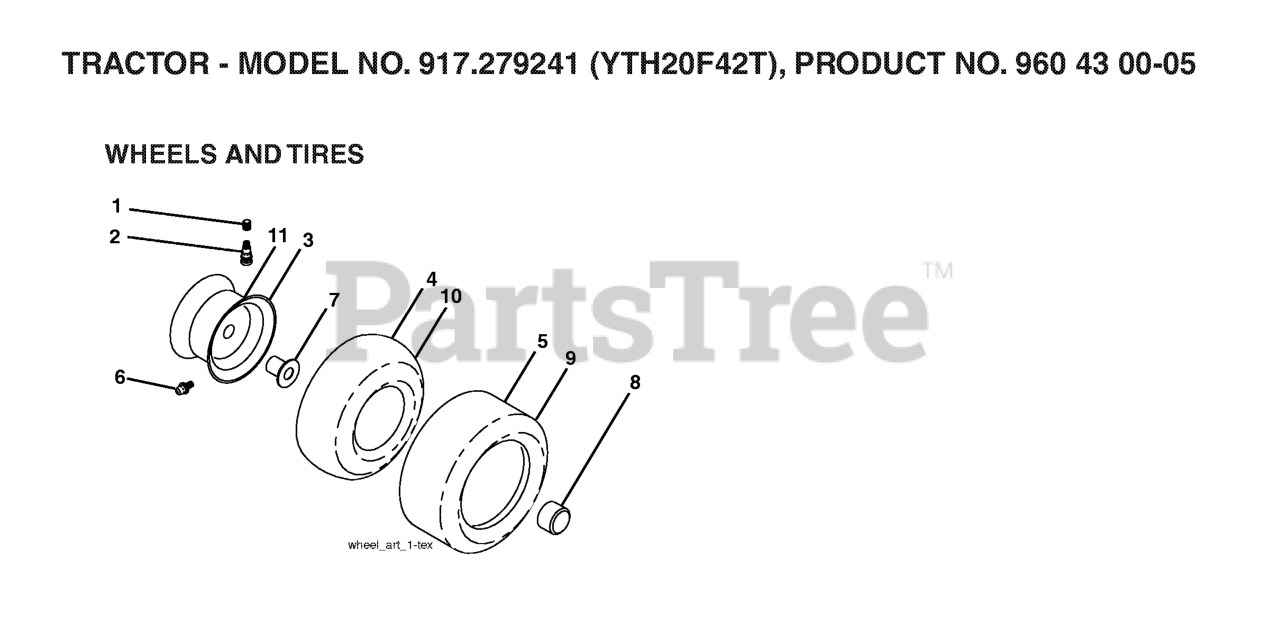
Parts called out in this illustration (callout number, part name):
2	VALVE STEM LT
3	RIM ASM 6" FRONT SILVER
4	TUBE.5.3/4.5/6
5	TIRE HEAVY DUTY
6	FITTING LT
7	BEARING T
8	CAP, AXLE BLK
9	TIRE.20X8-8.TURF.SAVER
10	TUBE
11	RIM ASM 8" REAR SILVER
